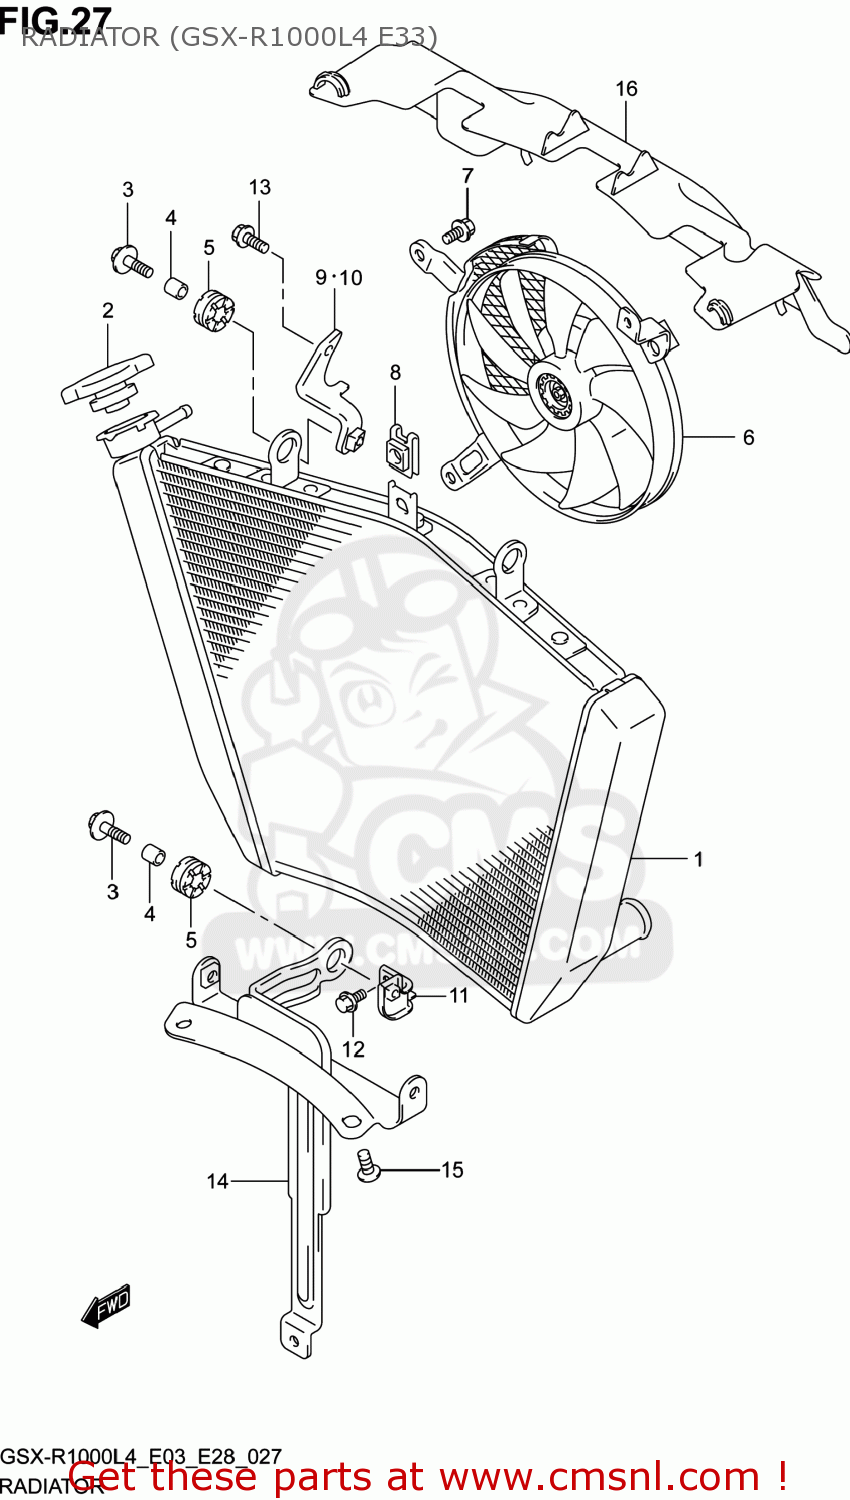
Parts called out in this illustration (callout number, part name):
1	RADIATOR ASSY,WATER
2	CAP,RADIATOR
3	BOLT(6X25)
4	SPACER(6.5X10X12)
5	CUSHION
6	FAN ASSY,RADIATOR
7	BOLT,FAN ASSY
8	NUT,FAN ASSY
9	BRACKET,RADIATOR,R
10	BRACKET,RADIATOR,L
11	BRACKET,RDTR & OIL COOLER
12	BOLT
13	BOLT
14	BRACKET,RADIATOR SUPPORT
15	BOLT(6X10)
16	SHIELD,RADIATOR HEAT
